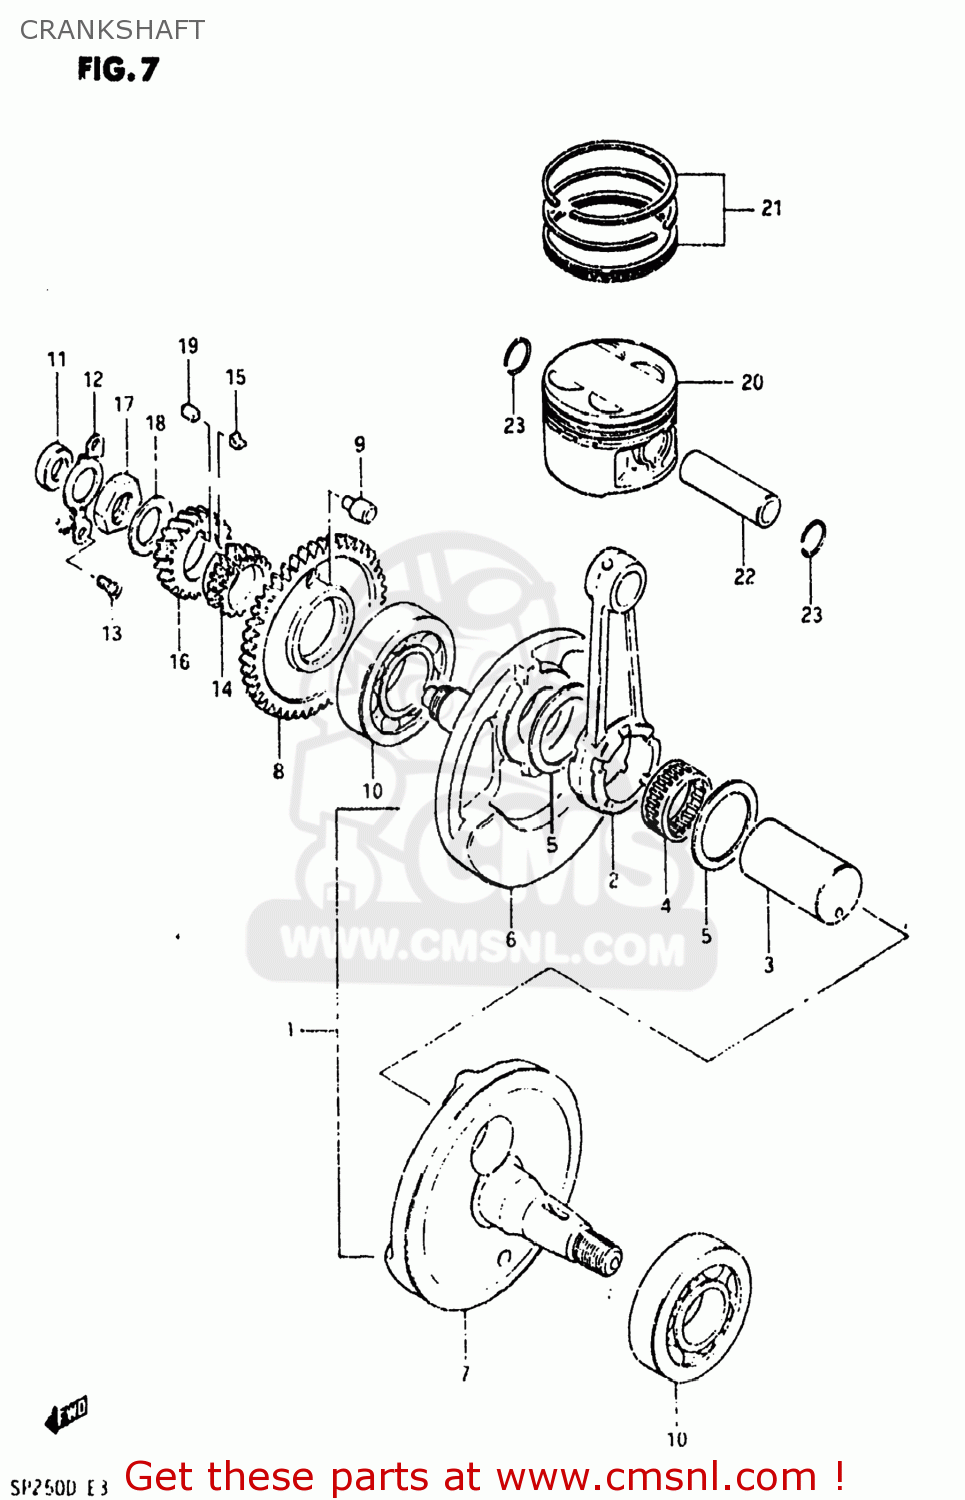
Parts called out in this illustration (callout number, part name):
1	CRANKSHAFT ASSEMBLY
2	CONNECTING ROD
3	PIN,CRANK
4	BEARING
5	WASHER(31X48.5X1)
6	CRANKSHAFT,R
7	CRANKSHAFT,LEFT
8	GEAR,CRANK BALANCER DRIVE
9	PIN
10	BEARING
11	SEAL,OIL(14X26X6)
12	RETAINER,CRANKSHAFT BEARING,R
13	SCREW
14	SPROCKET,CAM CHAIN DRIVE(NT:21
15	KEY,SPROCKET
16	GEAR,PRIMARY DRIVE NO.21
17	NUT (20MM)
18	WASHER
19	KEY
20	PISTON
21	RING SET,PISTON
22	PIN,PISTON
23	CIRCLIP
